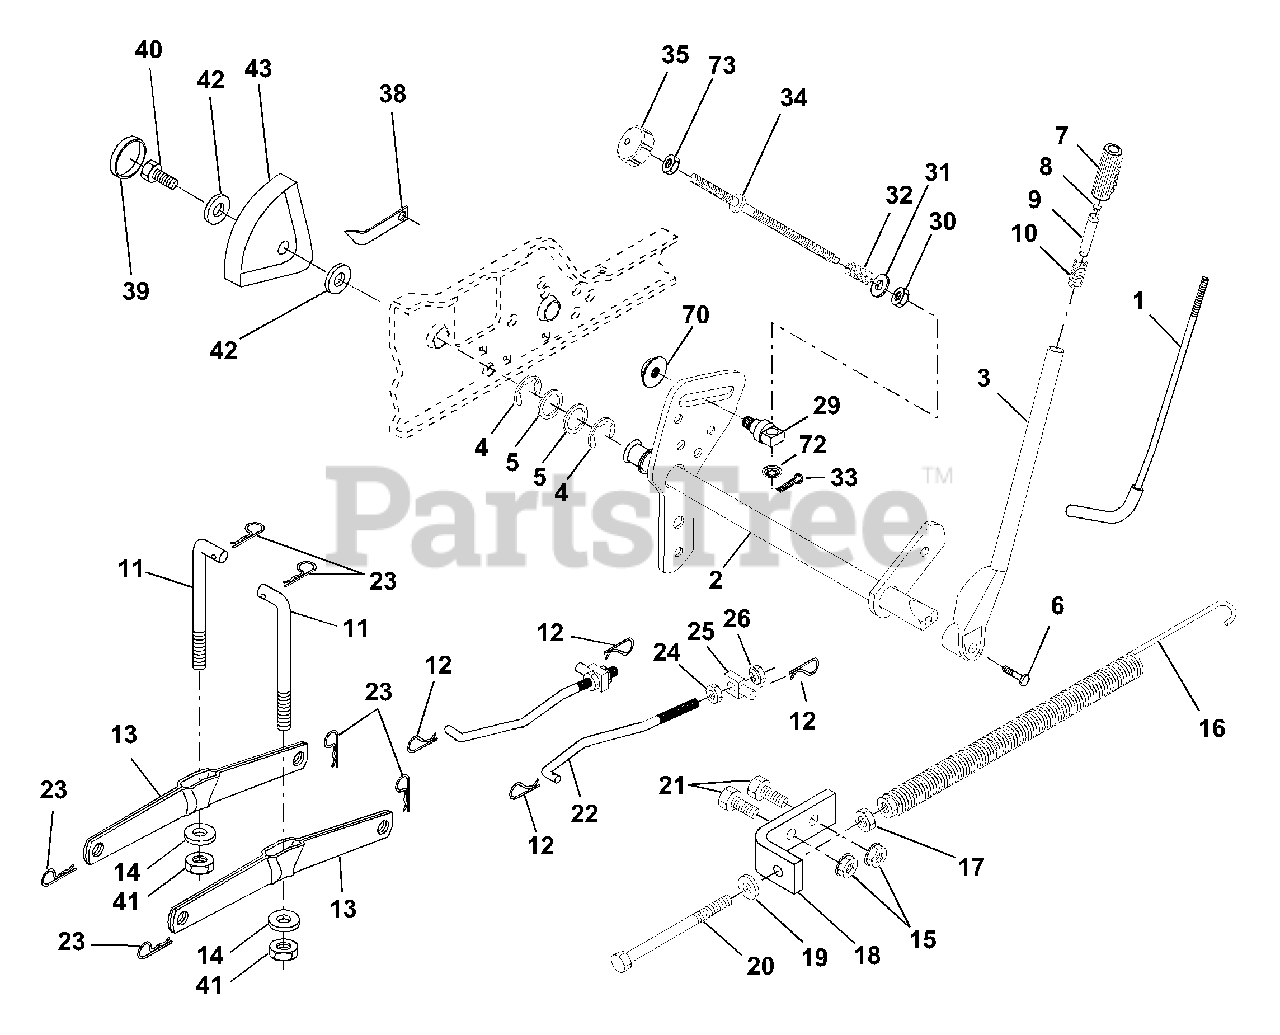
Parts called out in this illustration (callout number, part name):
1	Rod Asm., Lever
2	Shaft Asm., Lift Vgt
3	Lever Asm., Lift Rh
4	E-Ring Truarc #5133-87
5	Washer 29/32 x 1-1/4 x 16 Ga.
6	Bolt, Fin Hex 3/8-16 x 1-1/2
7	Grip, Handle
8	Button, Plunger
9	Plunger, Lever Lift
10	Spring 2-1/8"
11	Link Lift
12	Retainer, Spring
13	Arm, Suspension Vgt
14	Bearing
15	Nut, Crownlock 3/8-16
16	Spring Asm., Assist Lift
17	Nut, Hex Jam 3/8-16 Unc
18	Bracket, Spring Assist
19	Washer 13/32 x 13/16 x 16 Ga.
20	Bolt, Adjust Spring Assist
21	Bolt, Fin Hex 3/8-16 x 1
22	Link, Front
23	Retainer, Spring
24	Nut, Jam Hex 1/2-13 Unc
25	Trunnion
26	Nut, Lock W/Wsh 1/2-13 Unc
29	Trunnion Infin Height
30	Nut, Special
31	Washer 13/32 x 5/8 x 16 Ga.
32	Spring, Compression Inf Hgt
33	Pin, Cotter 3/32 x 1/2
34	Rod, Adj Lift
35	Knob, Inf 3/8-16 Unc
38	Pointer Height Indicator
39	Plug, Hole Blk. 1.485/1.515 Dia.
40	Screw 5/16-18 x 1
41	Nut, Crownlock 3/8-24
42	Washer 11/32 x 1-1/2 x 10 Ga.
43	Scale, Indicator Height
70	Nut Hex Flange Lock
72	Nut Push Phos & Oil
